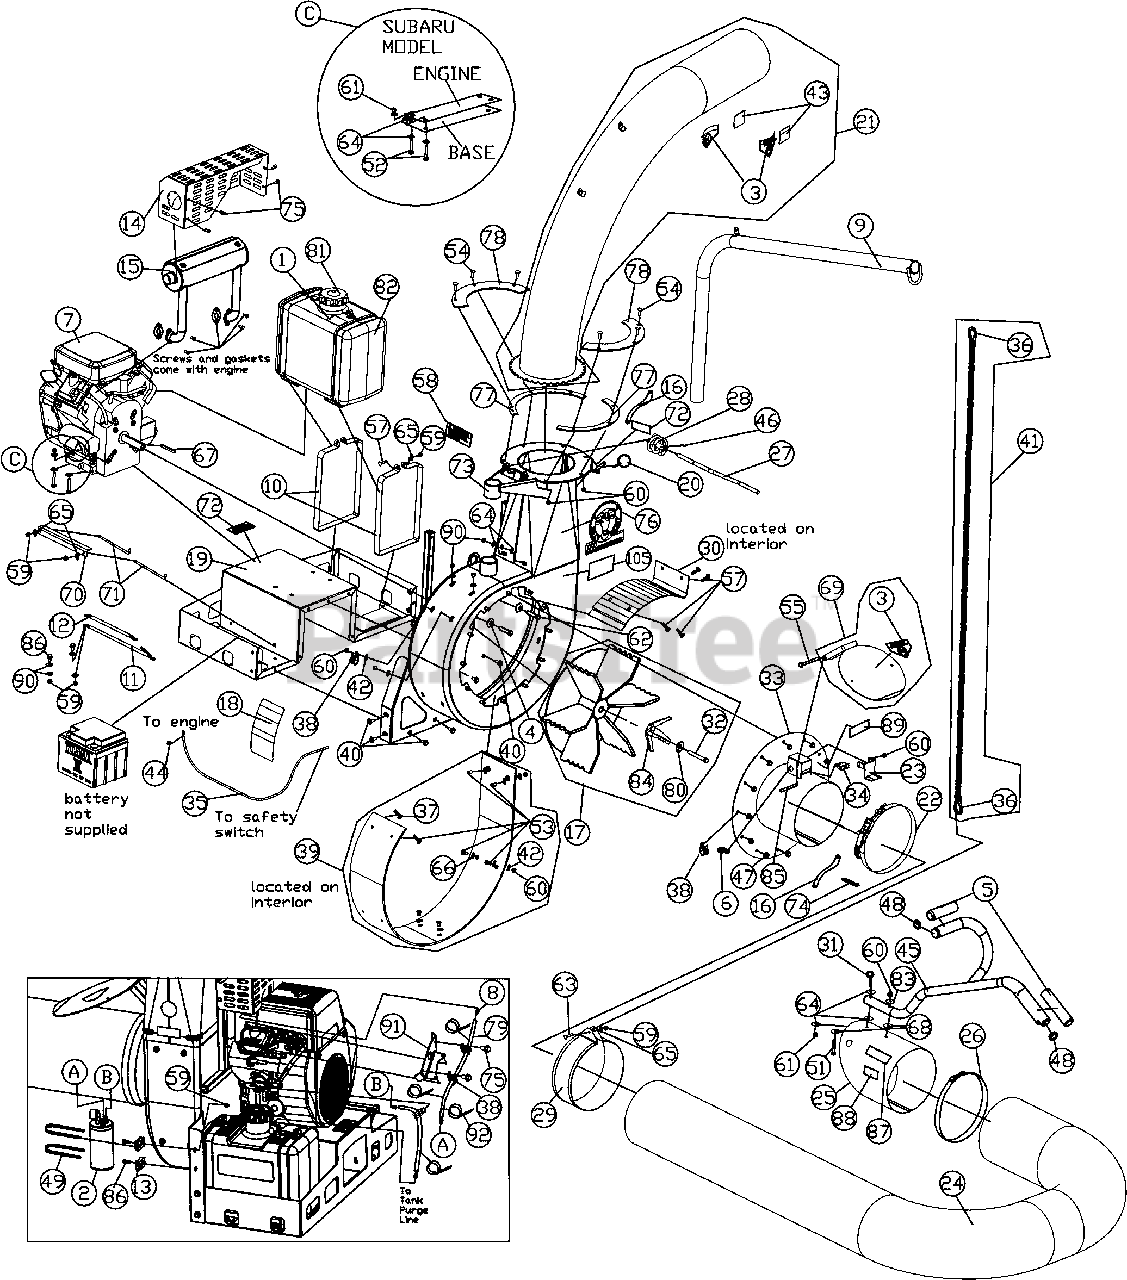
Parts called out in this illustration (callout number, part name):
1	LABEL WARNING EXPLOSIVE FUEL EN/SP
2	CANISTER CARBON 400cc
3	LABEL OPEI WARNING
4	WASHER TWISTED LOCK 7/16"
5	GRIP 1 1/4 ID X 9.5 LONG
6	STRAIN RELIEF HEYCO 1244
7	ENGINE 25 HP SUBARU
8	CLAMP FUEL LINE .50"
9	TUBE BOOM ARM DL
10	CLAMP GAS TANK
11	CABLE BATTERY RED 26"
12	CABLE BATTERY BLACK 10"
13	BRACKET CARBON CANISTER
14	EXHAUST GUARD
15	EXHAUST SUBARU
16	LANYARD 10" PLASTIC
17	IMPELLER DL
18	LABEL DL INSTRUCT/WARN
19	BASE ENGINE ASSY DL
20	LYNCH PIN
21	ELBOW ASSY DL
22	CLAMP QUICK RELEASE 12"
23	LEVER HOSE SWITCH
24	HOSE 12" x 10' INTAKE
25	NOZZLE INTAKE 12" FORMED
26	CLAMP HOSE 12"
27	SHAFT GEAR WORM
28	GEAR WORM
29	BAND HOSE BOOM 12" FORMED
30	CUT OFF LOADER
32	SCREWCAP 7/16-20X3 1/2" GR.8 WITH PATCH [TORQUE 55-60 ft.lb.]
33	INTAKE HOUSING DL 12"
34	PLUNGE SWITCH
35	HARNESS WIRE DL
36	HOOK SNAP SAFETY
37	SCREW BUTTON HEAD 5/16"-18 X 1"
38	CLAMP FUEL HOSE LINE
39	INTERIOR LINER
40	WASHER FACE BOLT
41	CHAIN HANG HOSE DL
42	WASHER 5/16" FLAT ZP
43	LABEL FLYING DEBRIS
44	WIRE TAP IN
45	HANDLE NOZZLE
46	ROLL PIN .1875 X 0.875
47	NUT WASHER FACE
48	PLUG TUBE INSERT 1.25 OD
49	CABLE TIE
50	LINE FUEL 1/4" ID X 24"
51	SCREWCAP 5/16-18 x 2
52	SCREWCAP 3/8-16 X 2
53	BUTTON HEAD 5/16-18 X 3/4
54	CARRIAGE BOLT 5/16x18x1
55	BOLT CARR. 5/16 - 18 x 3 1/2
56	CARRIAGE BOLT 3/8x16x1
57	CARRIAGE BOLT 1/4-20 X 1 3/4
58	LABEL WARNING ENGINE OVERHEAT
59	NUT LOCK 1/4"-20 HEX Z/P
60	NUT LOCK 5/16-18
61	NUT LOCK 3/8
62	SCREWCAP 7/16-14 X 2 GR 5 W/ PATCHLOCK
63	SCREWCAP 1/4-20 X 3" ZP
64	WASHER FLAT 3/8
65	WASHER 1/4 SAE
66	WASHER 5/16 SAE ZP
67	KEY 1/4" SQ X 4"
68	WASHER 5/16 FENDER
69	DOOR FLAPPER INTAKE DL 12"
70	BRACKET BATTERY DL
71	ROD BATTERY HOLD DOWN
72	LABEL WARNING SECURE
73	HOUSING ASSY DL
74	SAFETY PIN
75	SCREW 1/4-20 X 5/8 HWH
77	PLATE CLAMP SPLIT
78	PLATE CLAMP HALF
79	LINE FUEL 1/4" X 28"
80	WASHER LOCK 7/16" S/T MED
81	CAP TANK FUEL 6 GAL
82	TANK FUEL 6 GAL
83	WASHER 5/16 SAE
84	DEBRIS REDUCER DL25
85	SPACER 3/8 X 2 1/2
86	SCREWCAP 1/4-20 x 3/4
87	LABEL NOZZLE SECURE
88	LABEL WARNING NOZZLE
89	LABEL, WARNING LINER DL
90	WASHER 1/4" FLAT ZP
91	BRACKET PURGE LINE DL25
105	LABEL MADE IN USA
